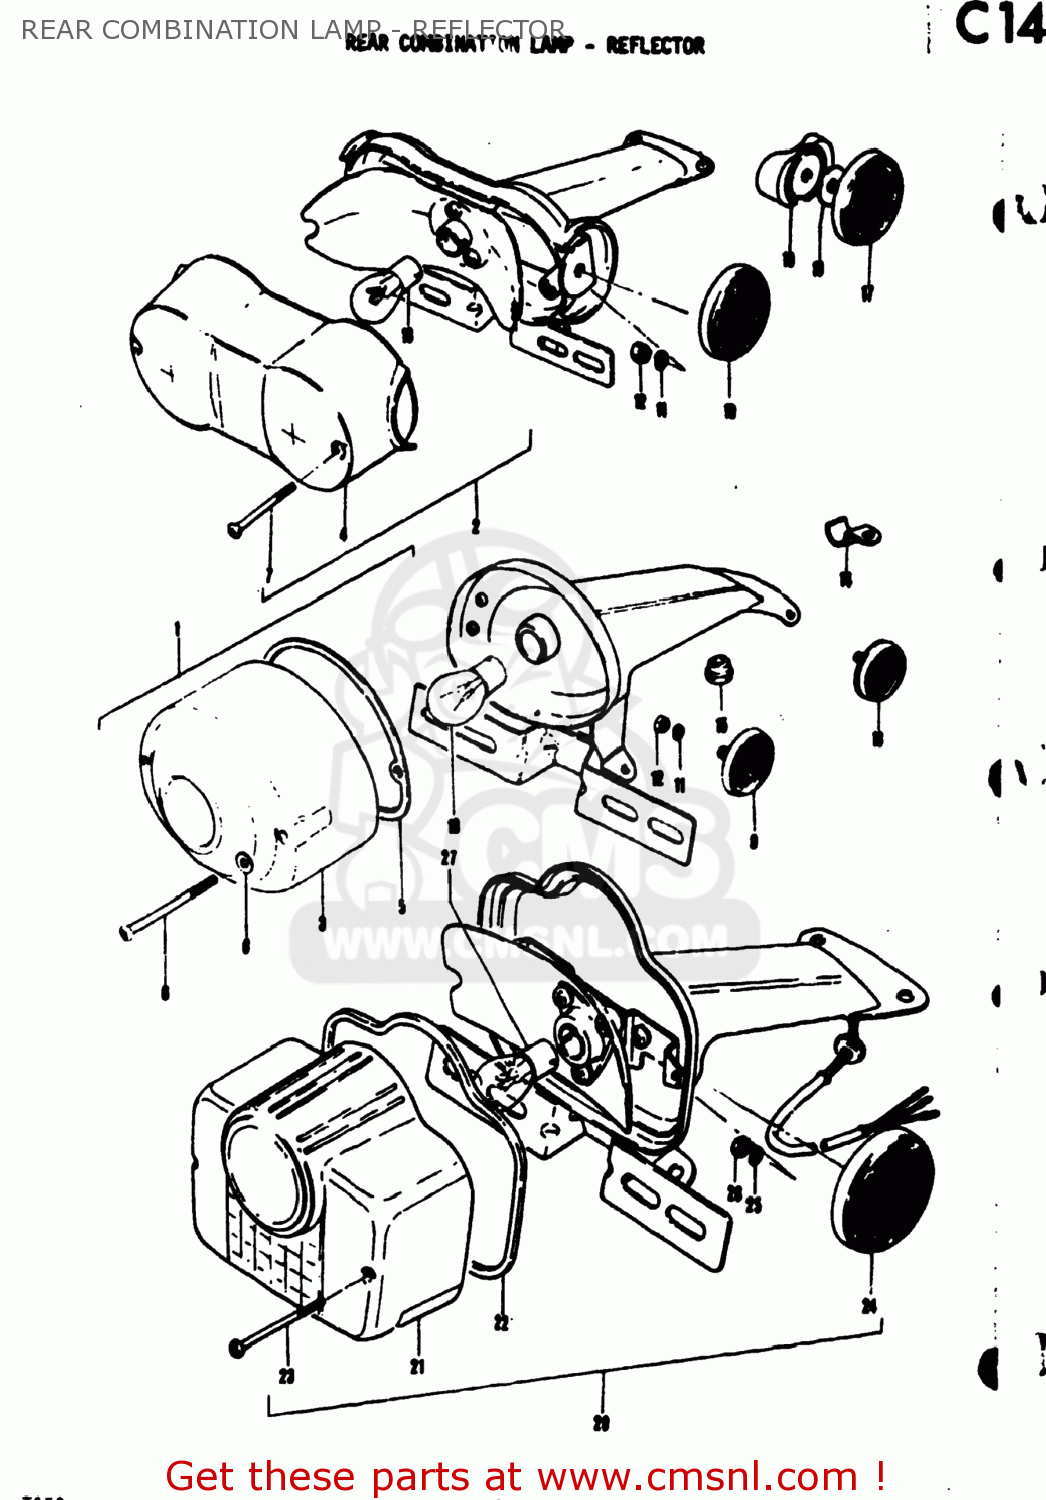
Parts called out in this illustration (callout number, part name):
1	CONVERSION KIT
2	CONVERSION KIT
3	LENS,REAR COMBINATION LAMP
4	LENS,REAR COMBINATION LAMP
5	GASKET,REAR COMBINATION LAMP LENS (NAS)
6	SCREW
7	SCREW
8	WASHER,REAR COMBINATION LAMP
9	REFLECTOR,REFLEX
10	REFLECTOR,REFLEX
11	LOCK WASHER
12	NUT
13	BULB(6V17/5.3W,STANLEY,A4813)
14	CLAMP
15	GROMMET
16	REFLEX REFLECTOR ASSEMBLY
17	REFLEX REFLECTOR ASSEMBLY
18	WASHER
19	SPACER
20	CONVERSION KIT
21	LENS,REAR COMBINATION LAMP
22	GASKET (NAS)
23	SCREW
24	REFLECTOR,REFLEX
25	LOCK WASHER
26	NUT
27	BULB(6V32/3CP,STANLEY)
